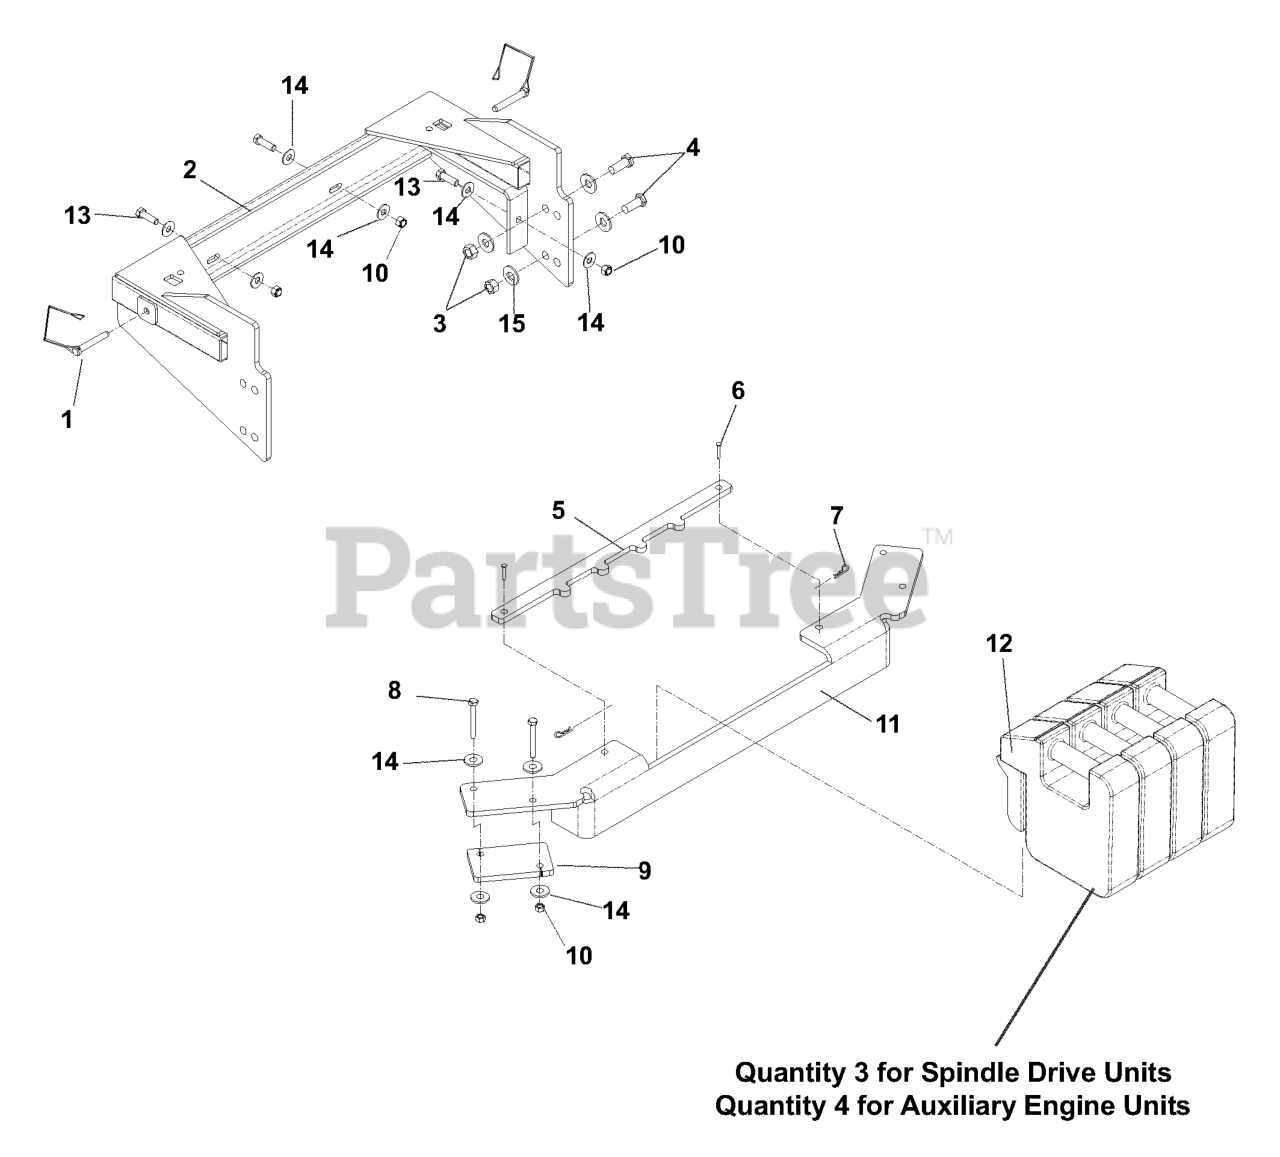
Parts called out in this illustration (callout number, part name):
1	PIN-WIRE LOCK
2	HIITCH
3	NUT 1/2 NYLOC
5	HOLD DOWN BAR
6	CLEVIS PIN
7	HAIR PIN #11
8	BOLT, 3/8-16 X 3 1/2
9	CLAMP PLATES-FRT WEIGHT BAR
10	NUT 3/8 NYLOC
11	FRONT WEIGHT BAR
12	FRONT WEIGHT PZ DFS
13	BOLT 3/8 X 1.25
14	FLAT WASHER 3/8
15	FLAT WASHER 1/2"
